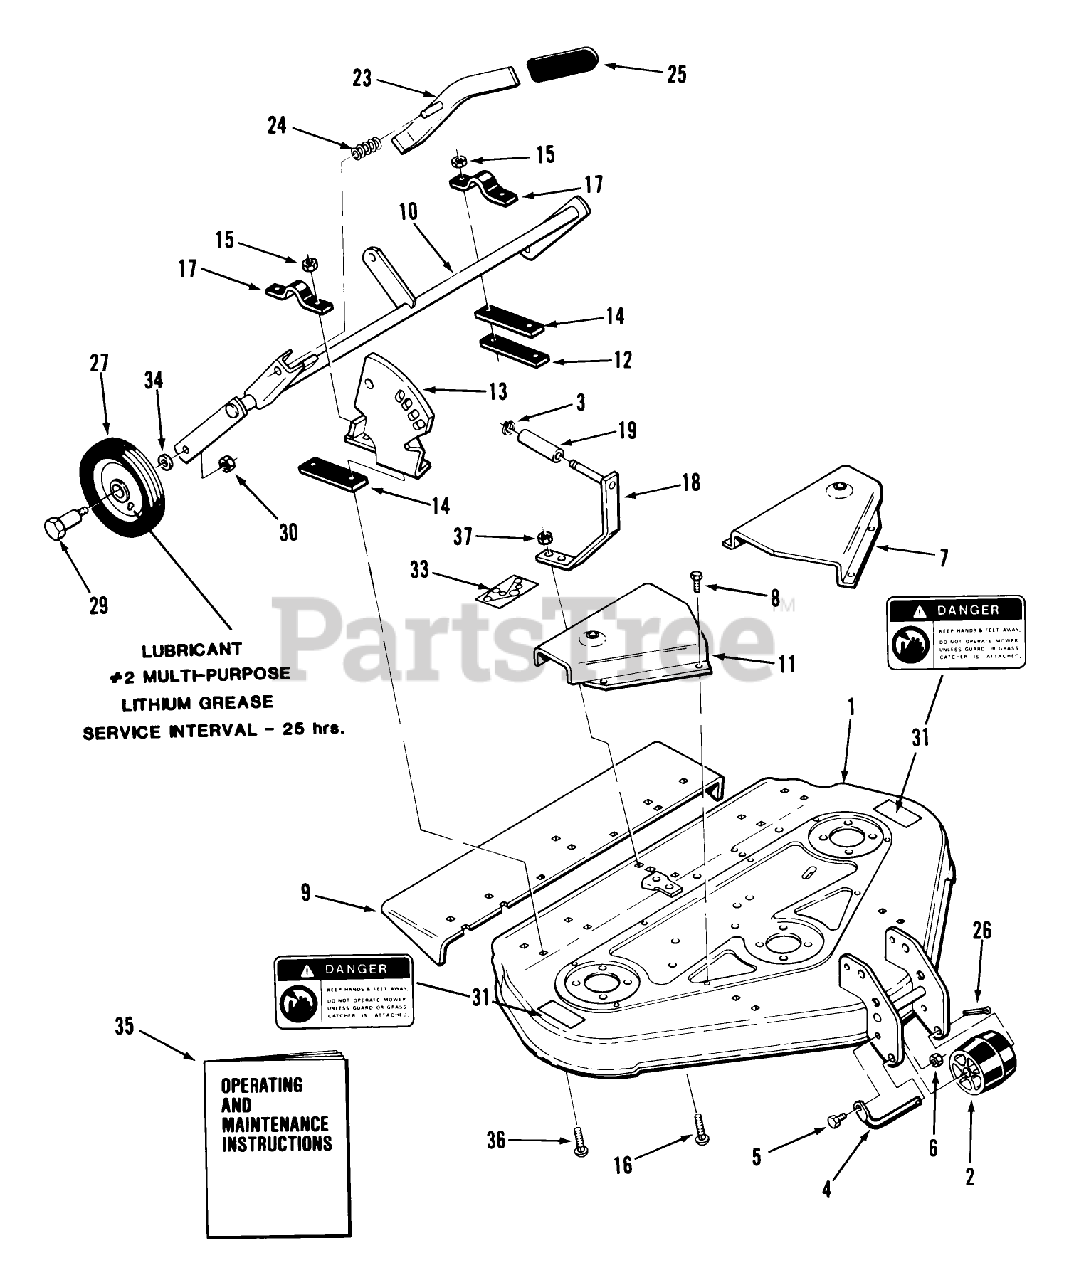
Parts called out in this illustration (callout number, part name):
1	Front Mount
2	ROLLER-CABLE
3	ROD CABLE ROLLER
4	STRAP-CABLE
5	ASSY-CABLE
5	ASSY CABLE
6	SPACER
7	Washer
8	Pop Rivet
9	GRIP RING
10	TRUNNION
11	GRIP RING
13	Washer
15	Hairpin Cotter
